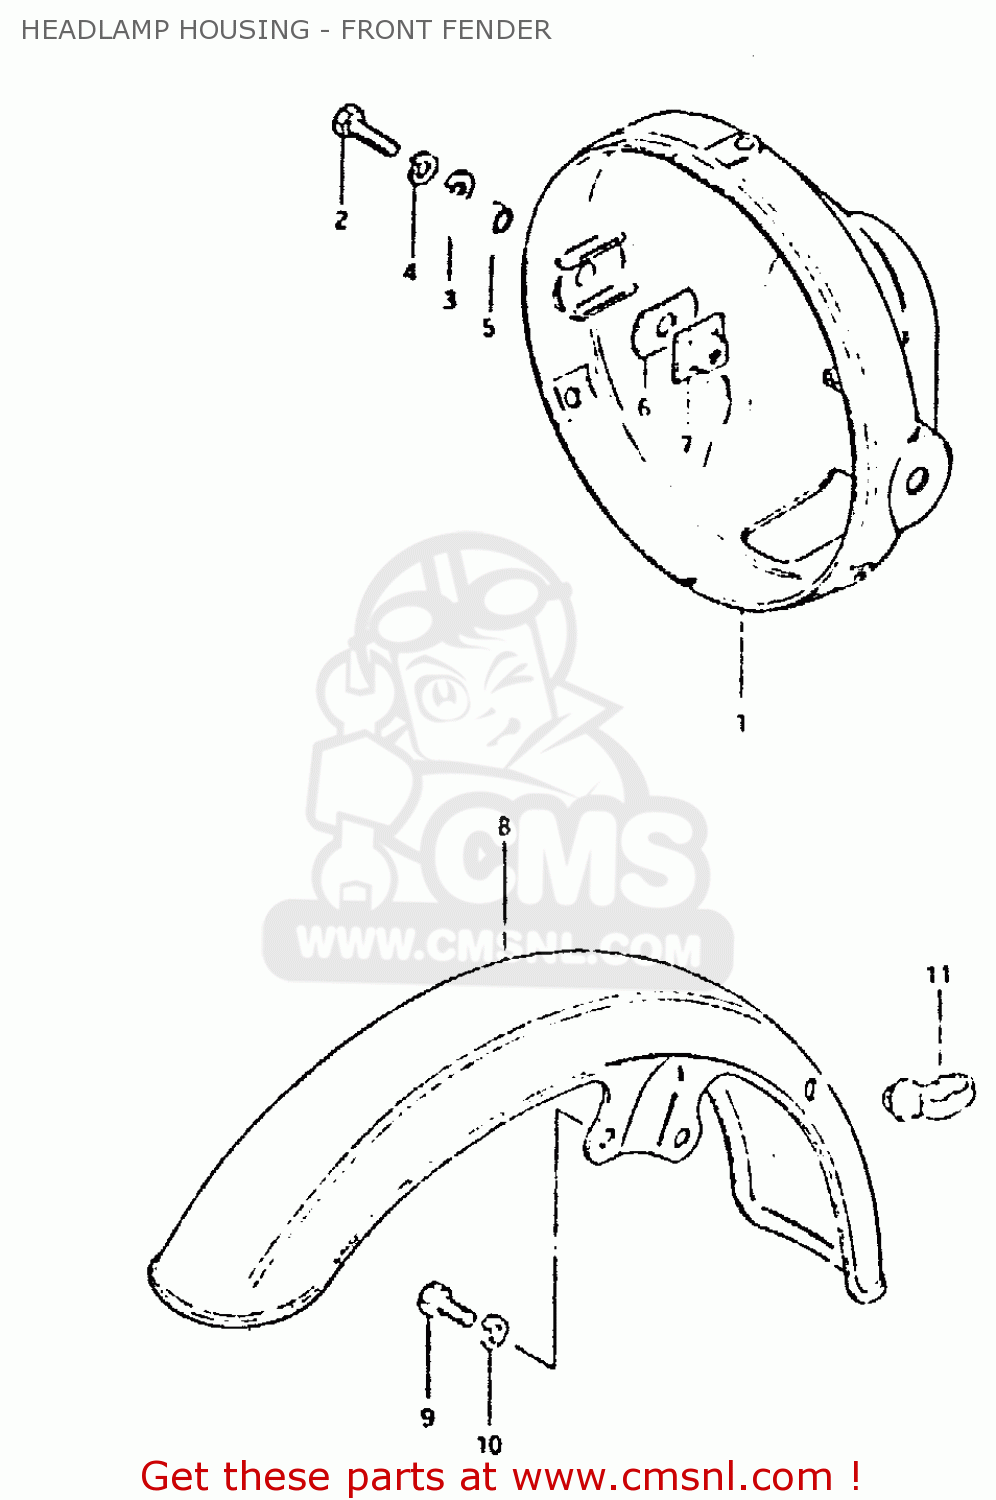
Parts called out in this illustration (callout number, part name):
1	HOUSING,HEADLAMP
2	BOLT
3	WASHER
4	LOCK WASHER
5	SPACER (8.8X12X7)
6	CUSHION
7	PLATE,HEADLAMP HOUSING
8	FENDER,FR
9	BOLT
10	LOCK WASHER
11	GUIDE,CABLE
